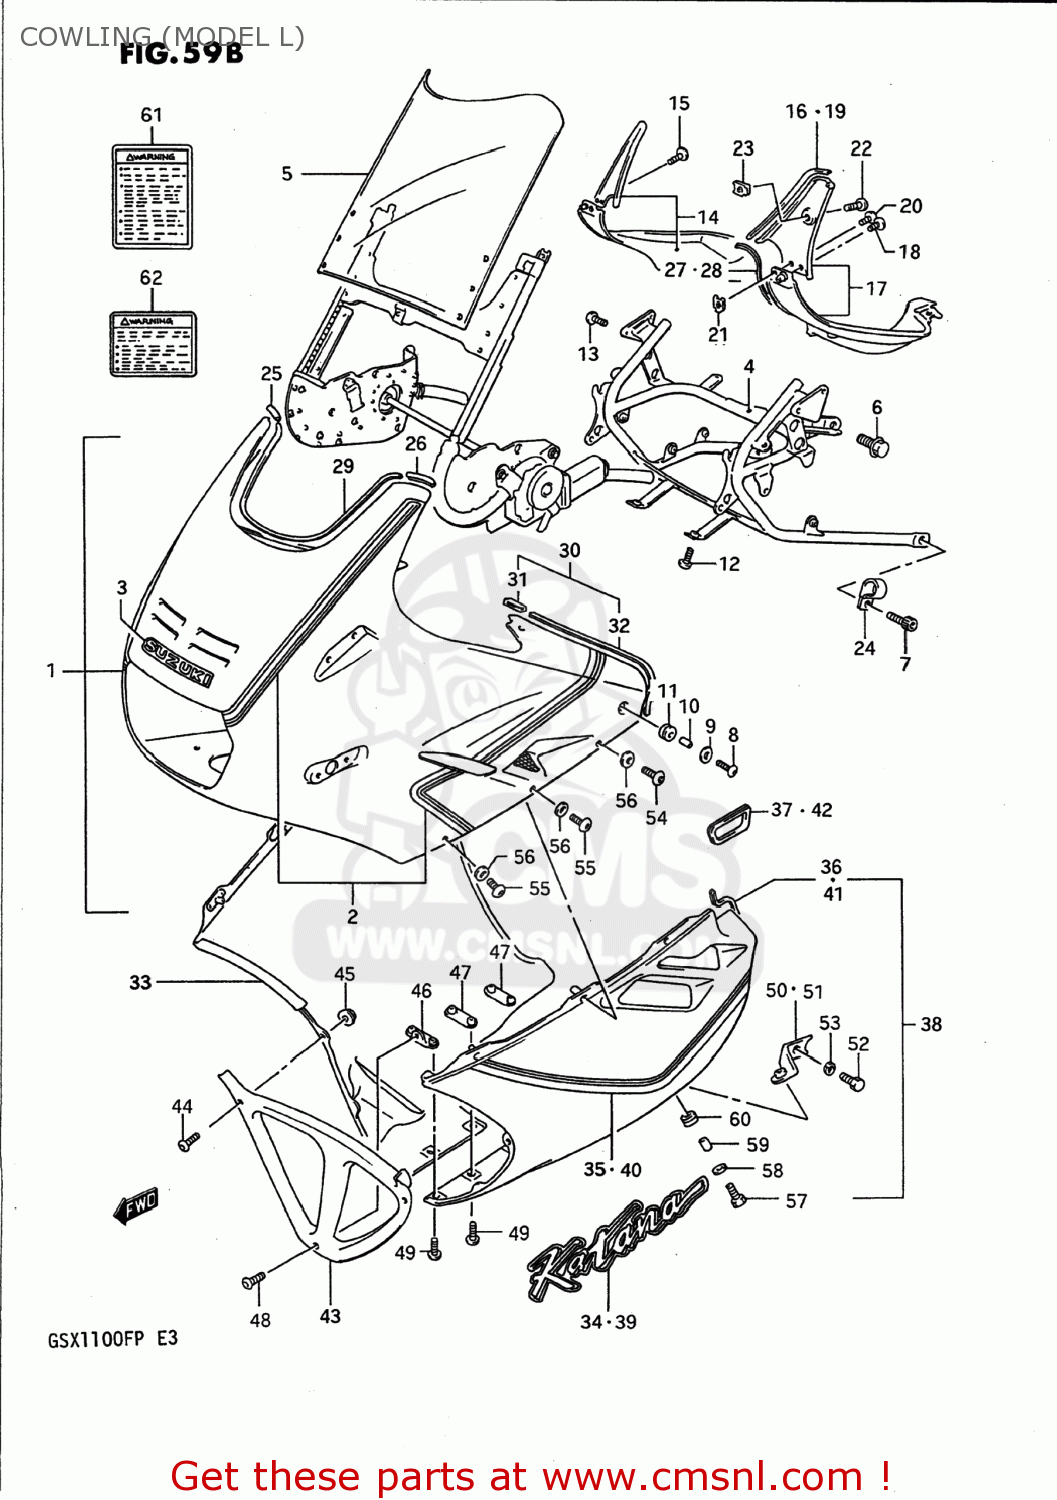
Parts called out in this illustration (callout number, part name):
1	BODY ASSEMBLY,COWLING
2	TAPE SET,COWLING,UPPER
3	EMBLEM (SUZUKI)
4	BRACE,COWLING
5	WINDSCREEN
6	BOLT(10X12)
7	BOLT
8	SCREW(6X20)
9	WASHER(6.5X18X1)
10	SPACER
11	CUSHION
12	SCREW(6X16)
13	SCREW 6X12
14	PANEL ASSY,R
15	SCREW
16	MOLDING,COWL.
17	PANEL ASSY,L
18	SCREW
19	MOLDING,COWL.
20	SCREW, FRONT & REAR
21	NUT
22	SCREW
23	NUT
24	CLAMP
25	CAP,PANEL & COWLING,R
26	CAP,PANEL & COWLING,L
27	MOLDING,COWLING PANEL,R
28	MOLDING,COWLING PANEL
29	MOULDING
30	MOLDING,COWLING BODY SIDE
31	COVER,MOLDING END
32	MOLDING,COWLING BODY SIDE
33	COVER ASSEMBLY,COWLING,LOWER
34	EMBLEM,COWLING,LOWER
35	TAPE,COWLING,LOWER,RIGHT
36	MOLDING,COWLING,LOWER
37	MOLDING,INLET
38	COVER ASSEMBLY,COWLING,LOWER
39	EMBLEM,COWLING,LOWER
40	TAPE,COWLING,LOWER,LEFT
41	MOLDING,COWLING,LOWER
42	MOLDING,INLET
43	COVER,COWLING,LOWER,FRONT
44	SCREW(5X14)
45	NUT
46	BRACE,COWLING LWR COVER
47	BRACE,COWLING LWR COVER RR
48	SCREW(6X12)
49	SCREW(6X16)
50	BRACE,COWLING LWR,R
51	BRACE,COWLING LWR,L
52	BOLT 8X12
53	LOCK WASHER
54	SCREW(6X20)
55	SCREW(6X16)
56	WASHER
57	SCREW(6X20)
58	WASHER(6.5X18X1)
59	SPACER(6.4X9.2X12)
60	CUSHION
61	LABEL (WARNING SCREEN)
62	LABEL
